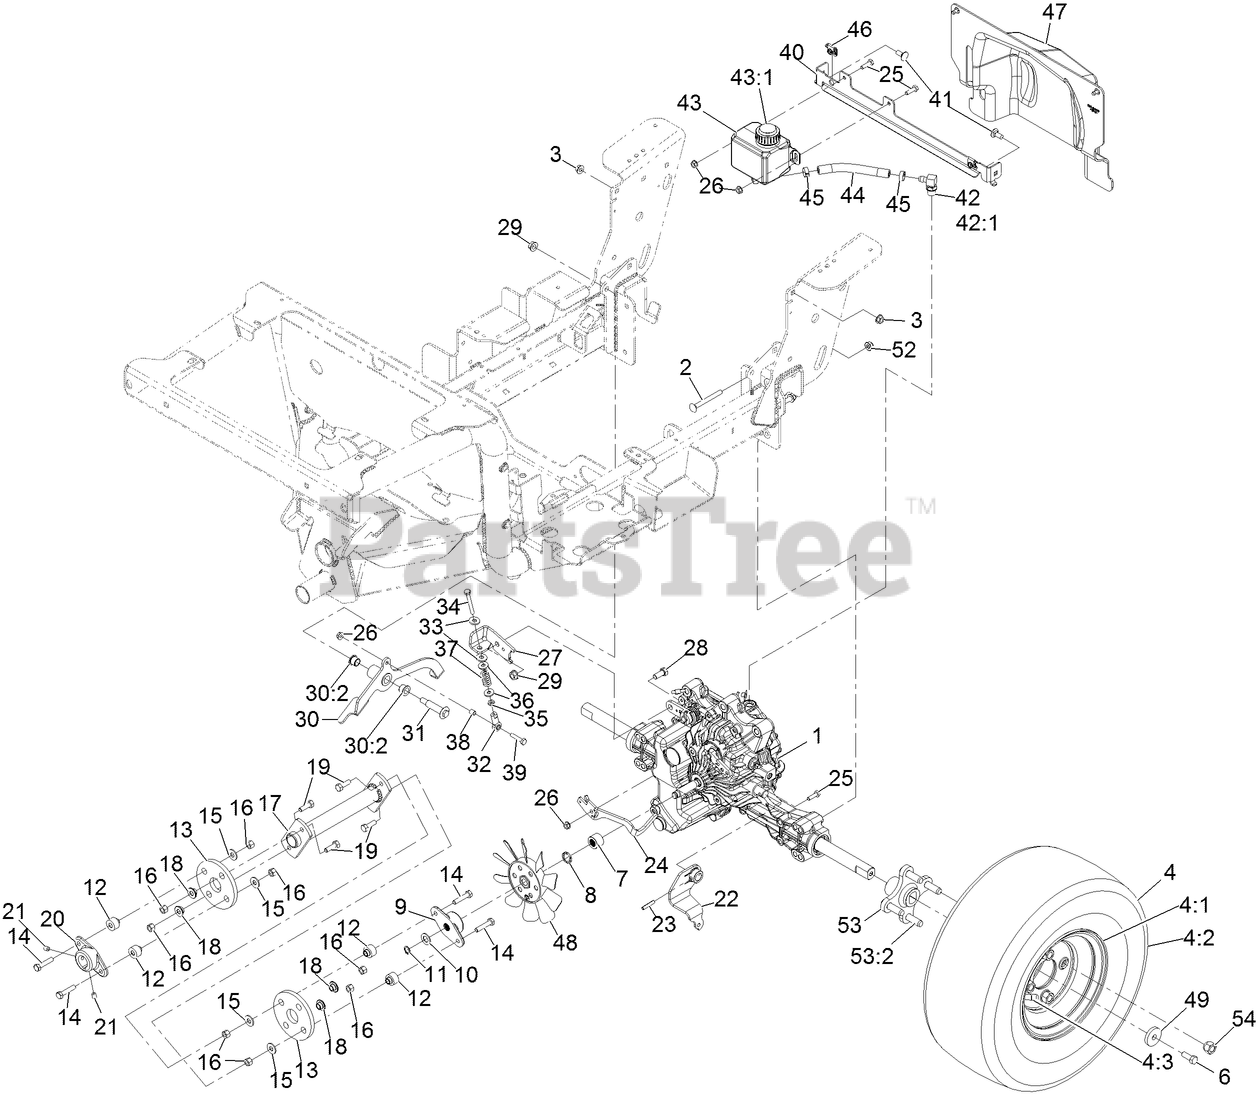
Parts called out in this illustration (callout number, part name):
1	TRANSAXLE
2	SCREW-CARR
4	Wheel And Tire ASM(18X7.5-8)
4:1	TIRE-4 PLY
4:2	Wheel, 8 X 5.375
4:3	Stem-Valve
6	SCREW-HH
7	SPACER-SHAFT, INPUT
8	WASHER-SPRING
9	HUB-SHAFT, TRANSAXLE
10	SPACER
11	RING-RETAINING
12	SPACER-COUPLING, RUBBER
13	COUPLING-RUBBER
14	SCREW-HH
15	WASHER-FLAT
16	NUT-HEX
17	Drive Shaft ASM, Welded
18	SPACER-COUPLER, RUBBER
19	SCREW-HH
20	HUB-SHAFT, ENGINE
21	SETSCREW
22	ARM-MOTION
23	PIN-SPIRAL
24	ARM-RELEASE
25	SCREW-HH
27	ARM-BRAKE
28	SCREW-HH
30	BRAKE LEVER ASM
30:2	BEARING-FLANGE
31	BOLT-SHOULDER
32	ROD END-BALL JOINT
33	WASHER-SPRING
34	SCREW-HH
35	NUT-JAM
36	WASHER-FLAT
37	SPRING-COMPRESSION
38	SPACER
39	SCREW-HH
40	BRACKET-MOUNT, TANK
41	SCREW-CARR
42	FITTING-90 DEG
42:1	O-RING
43	TANK ASM
43:1	CAP-TANK
44	HOSE-EXPANSION
46	RECEPTACLE-CLIP, MINI
47	TRANSAXLE COVER ASM
48	FAN-7 INCH
49	WASHER-CLUTCH
52	NUT-HF, NI
53	WHEEL HUB ASM
53:2	STUD-TYPE, DRIVE
54	NUT-LUG
